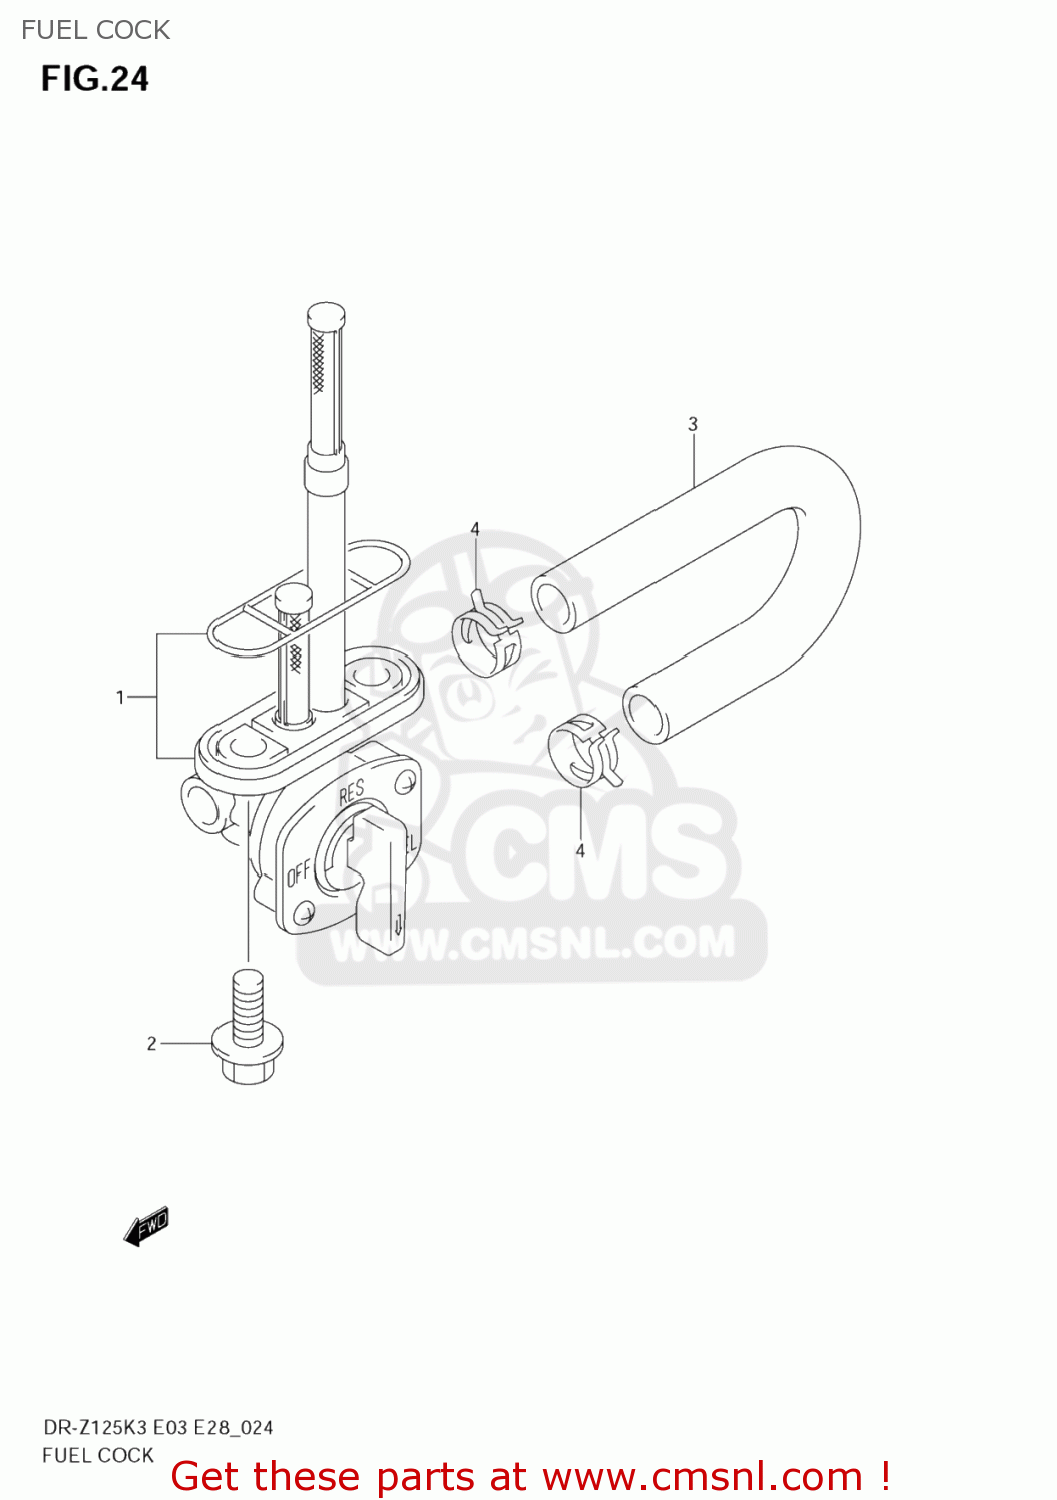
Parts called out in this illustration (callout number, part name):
1	COCK ASSY,FUEL
2	BOLT
3	HOSE, FUEL
4	CLIP
